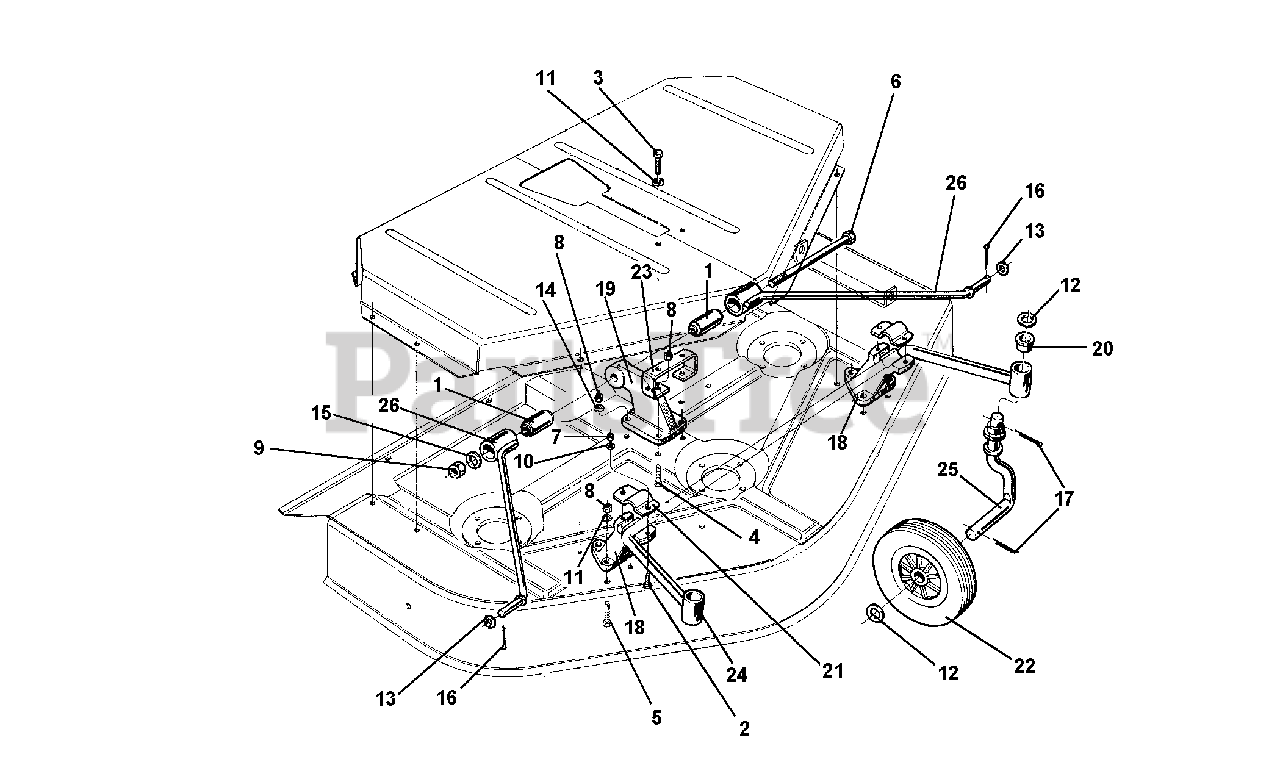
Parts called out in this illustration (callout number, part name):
1	SILENTBLOC 14 X 30 X 45 X 49
2	SCREW M6 X 25
3	SCREW M8 X 16
4	SCREW M8 X 25
5	SCREW M8 X 35
6	SCREW TE M14 X 160 UNI 5737
7	NUT, SELF LOCKING M6
8	NUT, SELF LOCKING M8
9	NUT, SELF LOCKING M14 STANDARD
10	WASHER, FLAT 6.4
11	WASHER, FLAT 8.4
12	WASHER, FLAT 21 UNI 1736
13	FLAT WASHER
14	WASHER, LOCK 8.4
15	WASHER, LOCK 15
16	PIN, COTTER A 3 X 20 UNI 1336
17	PIN, COTTER A 4 X 30 UNI 1336
18	SUPPORT WHEEL AXLE
19	SUPPORT, CRANKCASE
22	FRONT RUBBER WHEEL
23	SUPPORT, PROTECTIONS
24	AXLE, WHEELS
